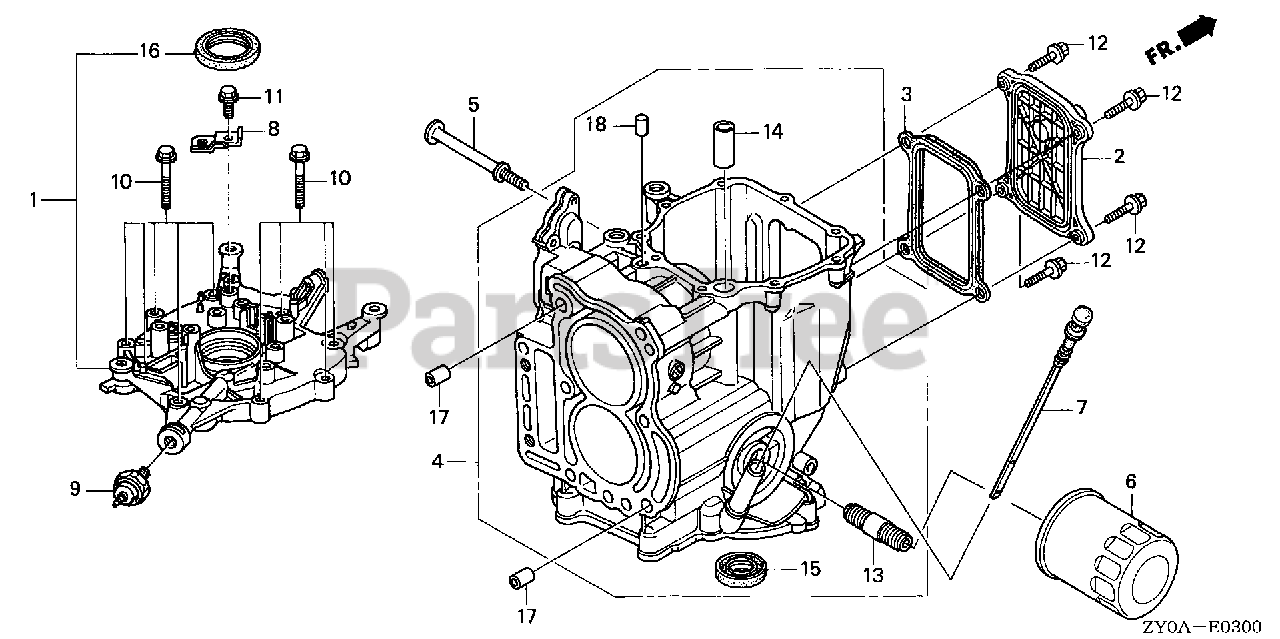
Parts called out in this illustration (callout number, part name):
1	COVER ASSY., CRANKCASE
2	COVER, CRANKCASE SIDE
3	GASKET, CRANKCASE SIDE COVER
4	BLOCK ASSY., CYLINDER *NH8* (DARK GRAY)
5	STOPPER, ENGINE SIDE
6	FILTER, OIL (TOYO ROKI)
7	DIPSTICK, OIL
8	BRACKET, CLIP B
9	SWITCH ASSY., OIL PRESSURE
10	BOLT, FLANGE (6X28)
11	BOLT, FLANGE (6X14) (CT200)
12	BOLT, FLANGE (6X22) (CT200)
13	HOLDER, OIL FILTER
14	PIN, DOWEL (14X20)
15	OIL SEAL (28X45X8)
16	OIL SEAL (35X50X8) (NOK)
17	PIN, DOWEL (10X12)
18	PIN B, DOWEL (8X14)
